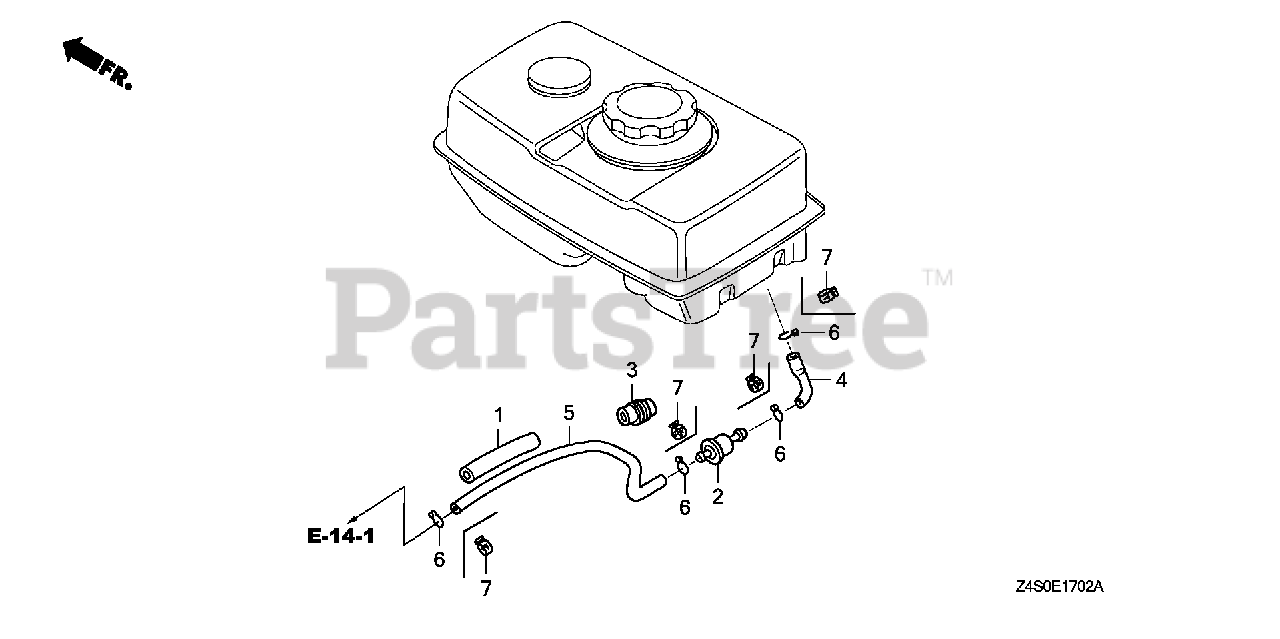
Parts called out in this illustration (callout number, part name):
1	RUBBER, SUPPORTER (50MM)
2	STRAINER, FUEL
3	RUBBER, FUEL (9X15X20)
4	TUBE, FUEL (4.5X35) (FKM)
4	BULK HOSE, FUEL (4.5X3000) (4.5X35)
5	TUBE, FUEL (4.5X110) (FKM)
5	BULK HOSE, FUEL (4.5X3000) (4.5X110)
6	CLIP, TUBE (B8)
7	CLAMP, TUBE (D8)
